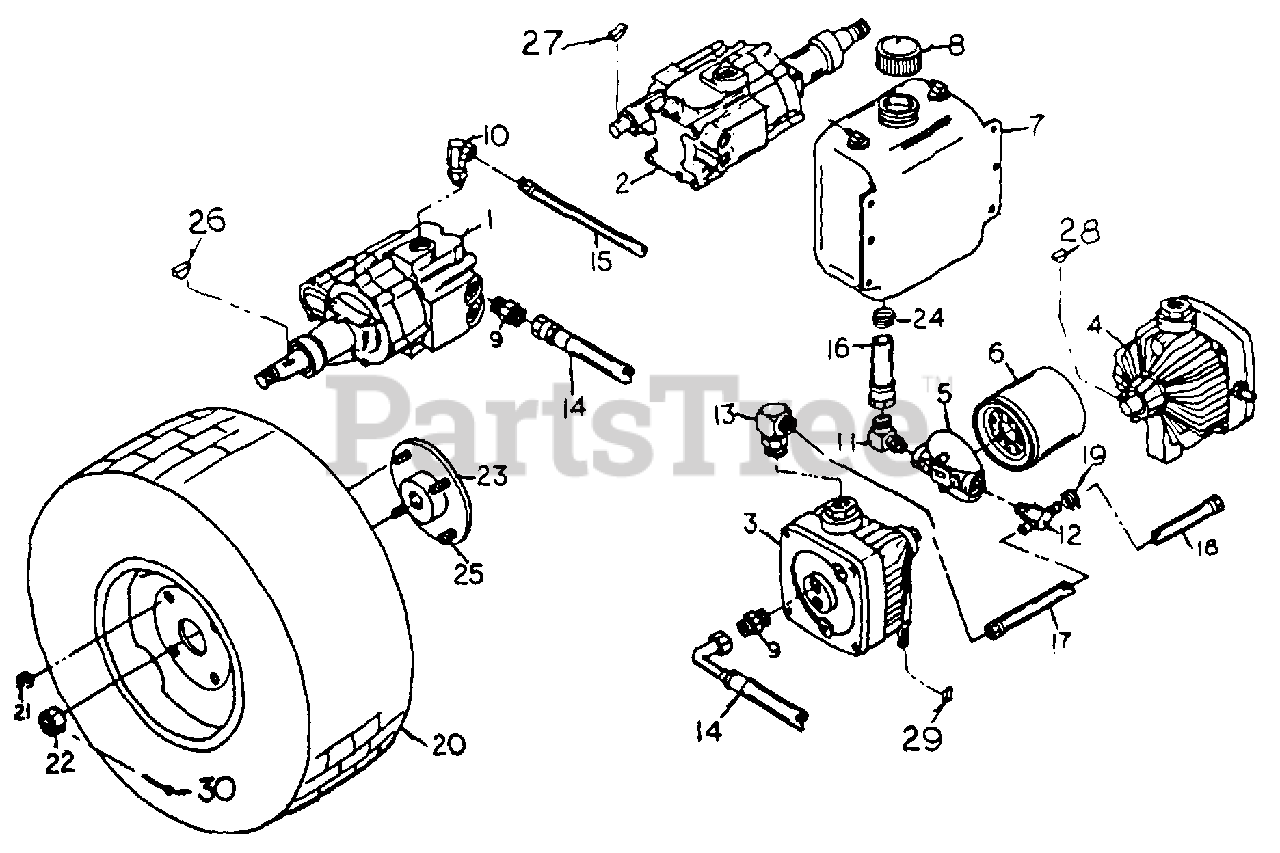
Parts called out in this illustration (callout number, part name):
1	WHEEL MOTOR - L.H.
2	WHEEL MOTOR - R.H.
3	PUMP - L.H.
4	PUMP - R.H.
5	HOUSING - Oil Filter
6	ELEMENT - Oil Filter
7	3 QT. OIL TANK
8	CAP - Oil Tank
9	FITTING - male tube male o-ring adp.
10	FITTING - male o-ring, 90° Female Pipe Swivel Adp.
11	FITTING - male o-ring, 90° Male Tube Adp.
12	FITTING - male o-ring, 1/2" Hose Barb Tee
13	FITTING - male o-ring, 90° Male Tube Adp.
14	HOSE - 1/2" ID x 28" Long
15	HOSE - 1/4" ID x 24" Long, Easy Couple
16	HOSE - 5/8" ID x 3-3/4" Long, Easy Couple
17	HOSE - 1/2" ID x 7-3/4" Long, Easy Couple
18	HOSE - 1/2" ID x 12" Long, Easy Couple
19	HOSE CLAMP - 1/2"
20	WHEEL ASS'Y - 18 x 9.50-8
20	WHEEL ASS'Y - 18 x 6.50-8
21	LUG NUT, 1/2-20
22	NUT - Wheel Motor
23	4-BOLT Wheel Hub
24	HOSE CLAMP - 5/8"
25	LUG BOLT - 1/2-20 x 1-1/4"
26	WOODRUFF KEY - 1/4" x 1"
27	WOODRUFF KEY - 3/16" x 3/4"
28	WOODRUFF KEY - 1/8" x 1/2"
29	WOODRUFF KEY - 1/8" x 3/8"
30	COTTER PIN - 1/8" x 1-3/4"
